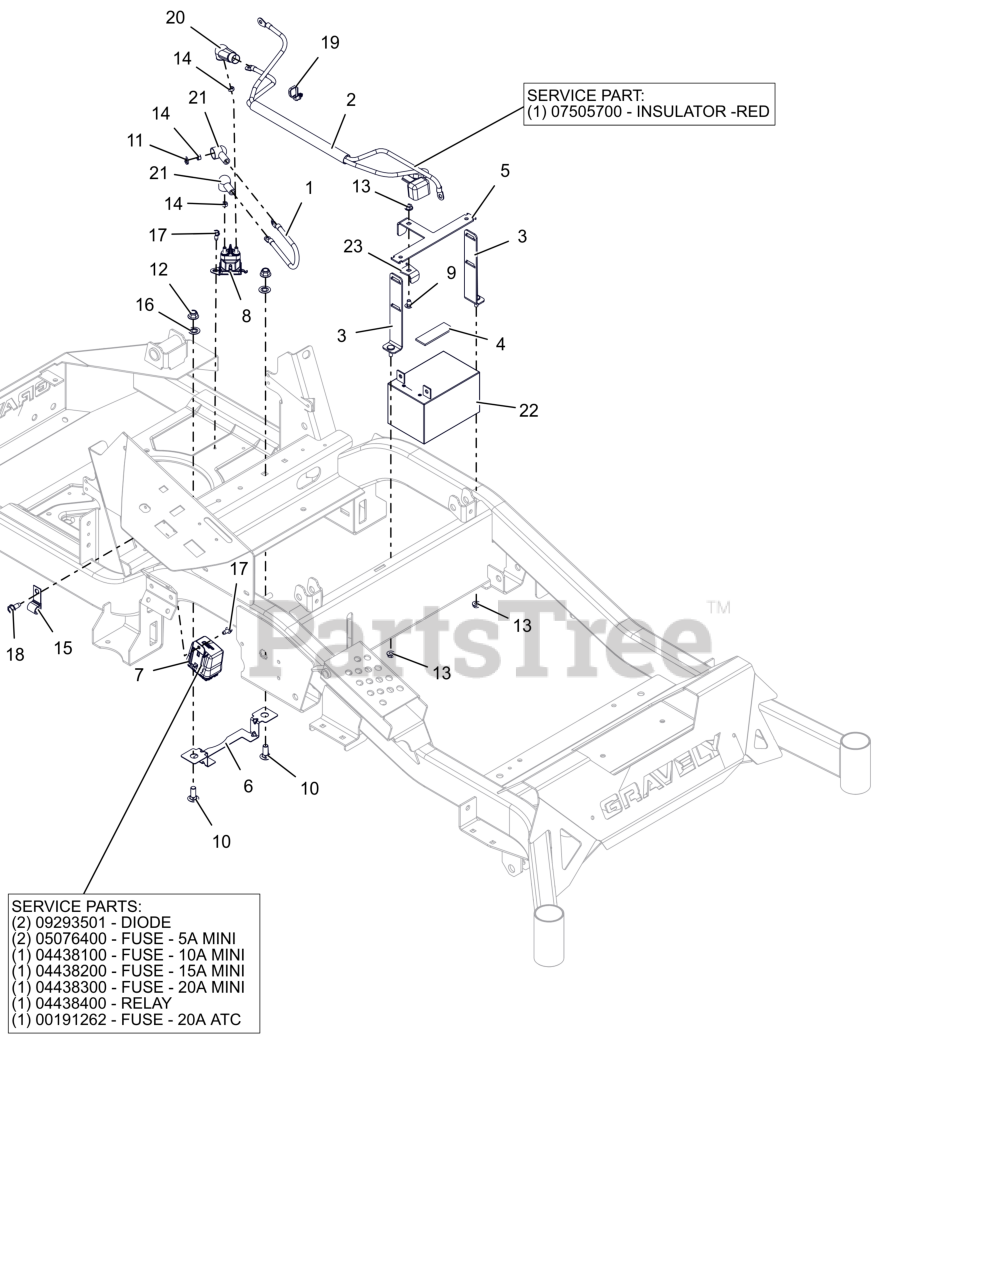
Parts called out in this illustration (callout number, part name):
1	CABLE, POS W/(2)1/4 RING 9.0LG
2	HARNESS, BATTERY HD
2	INSULATOR
3	WMT,BATTERY MOUNT HOLD DOWN
4	PAD,RBR 1.0"X3.0" W/ADHESIVE
5	BRKT, BATTERY TIE DOWN
6	GUARD, ELECTRICAL HARNESS
7	HARNESS, WIRE
7	DIODE, CONNECTOR SHELL
7	FUSE, 5 AMP MINI-ATC
7	FUSE,10 AMP MINI-ATC
7	FUSE,15 AMP MINI-ATC
7	FUSE,20 AMP MINI ATC
7	RELAY,MICRO5 TERML W/RESISTOR
7	FUSE, 20 AMP BLADE S/O
8	SOLENOID, STARTER (SEALED)
9	BLT, RHSN .25-20X.500 G5 ZCC
10	BLT, RHSN .38-16X1.00 G5 ZCC
11	WSHR,LK-REG .312X.078 ZCC
12	NUT,NYL-FLG .38-16 GF ZCC
13	NUT-LK-TOP-FLG .250-20 GF ZCC
14	NUT-STD M6-1.0 ZCC
16	WSHR, RETAINING .35X.88X.03 NYL
17	SCR-TAP .25-20X.50 HWH ZCC
18	SCR,TAP .312-18X.75 HWH TR ZCC
19	CABLE TIE W/ TREE (.25 HOLE)
20	BOOT, .65ID POS
21	BOOT, EYELET TERMINAL
22	BATTERY, 12V 12A -190CCA
23	BRKT, BATTERY HOLD
